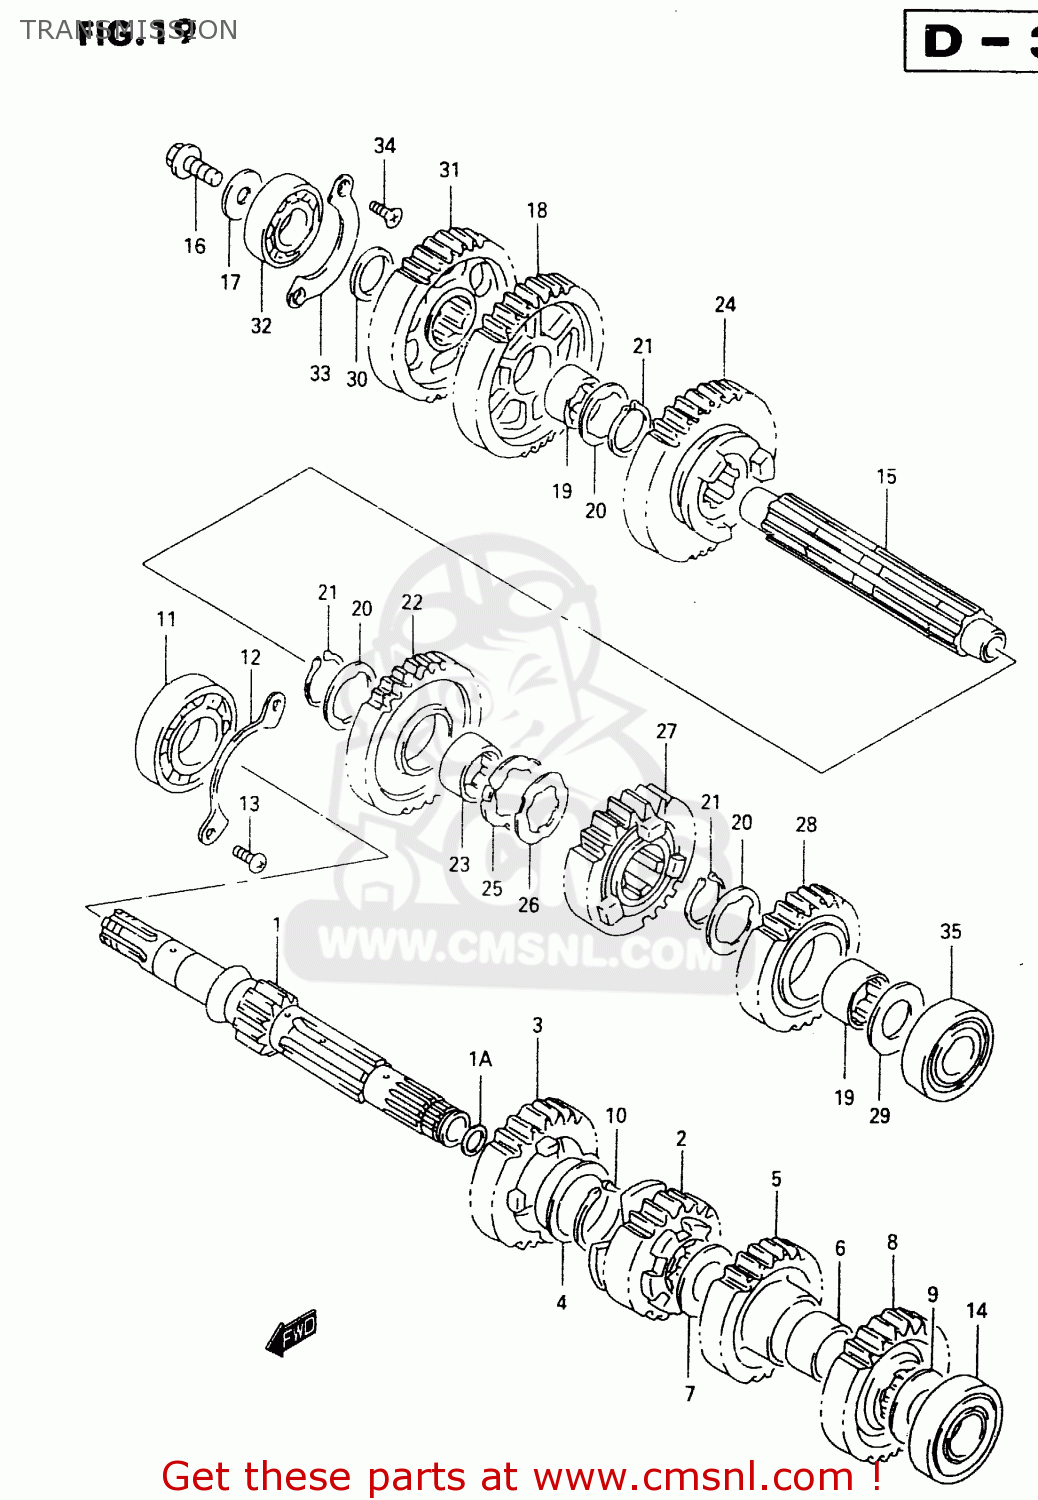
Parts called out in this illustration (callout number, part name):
1	SHAFT,COUNTER(NT:12)
1A	O RING(D:1.9,ID:16.6)
2	GEAR,SECOND DRIVE (NT:17)
3	GEAR,3RD DRIVE(NT:21)
4	BUSH(28X32X2)
5	GEAR,FOURTH DRIVE (NT:24)
6	BUSH,4TH DRIVE GEAR
7	SHIM(22X32X1)
8	GEAR,5TH DRIVE(NT:26)
9	SHIM(20X32X1)
10	CIRCLIP
11	BEARING(25X62X17)
12	RETAINER,CNTR SHAFT BEARING
13	SCREW
14	BEARING(20X52X15)
15	SHAFT,DRIVE
16	BOLT(10X24)
17	WASHER
18	GEAR,1ST DRIVEN(NT:36)
19	BUSH
20	WASHER,LOCK
21	CIRCLIP
22	GEAR,2ND DRIVEN(NT:31)
23	BUSH,3RD DRIVEN GEAR
24	GEAR,THIRD DRIVEN (NT:28)
25	WASHER
26	WASHER,LOCK
27	GEAR,FOURTH DRIVEN (NT:25)
28	GEAR,5TH DRIVEN(NT:23)
29	WASHER
30	WASHER(22X32X3)
31	GEAR,OVER DRIVING DRIVE(NT:34)
32	BEARING(22X56X16)
33	RETAINER,CNTR SHAFT BEARING
34	SCREW
35	BEARING(20X52X15)
